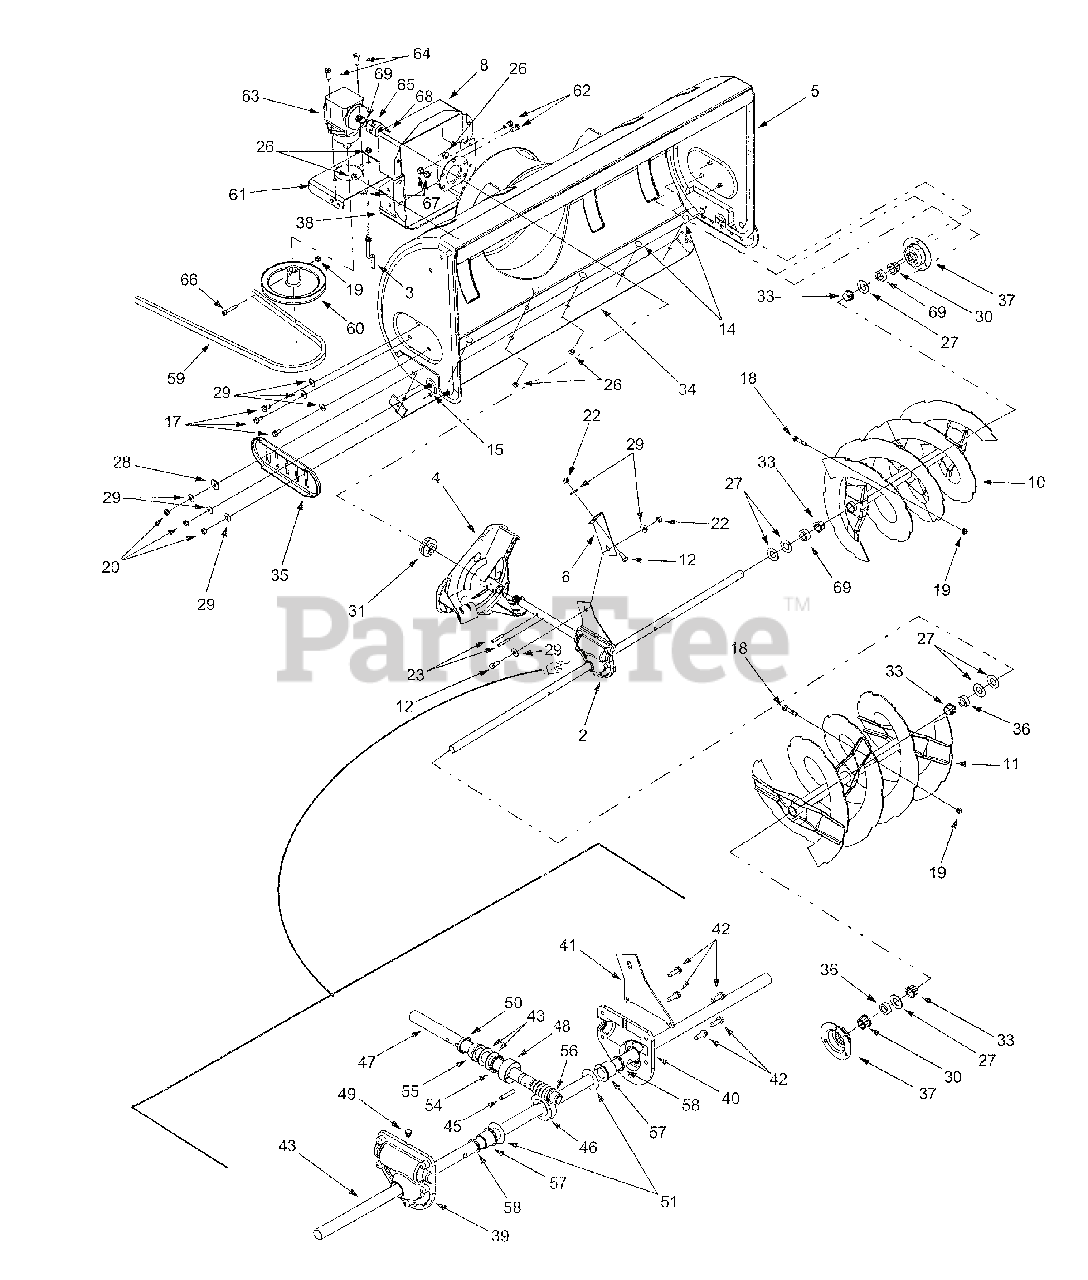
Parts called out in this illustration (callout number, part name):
1	Bearing Housing, 1.85 ID
2	Auger Gear Case
3	Belt Keeper Rod
4	Impeller Assembly, 12"
10	LH Spiral Auger, 40"
11	RH Spiral Auger, 40"
12	Hex Cap Screw, 5/16-24 x .75
13	Carriage Screw, 1/4-20 x .5
14	Carriage Bolt, 5/16-18 x .62
15	Splined Carriage Screw, 5/16-18 x 1.0
16	Carriage Bolt, 5/16-18 x .75
17	Self Tapping Screw, 5/16-18 x .625
18	Shear Bolt, 5/16-18 x 1.5
19	Hex Lock Nut, 5/16-18
20	Hex Nut, 5/16-18
21	Hex Flange Lock Nut, 1/4-20
22	Hex Nut, 5/16-24
23	Spirol Pin, 1/4 x 1-1/2
24	Spirol Pin, .125 x .812
25	Adapter Chute
26	Flange Lock Nut, 5/16-18
27	Flat Washer, .76 x 1.49 x .06
28	Flat Washer, .344 x 1.125 x .12
29	Bell Washer, .340 x .872
30	Hex Flange Bearing, .75 ID
31	Flange Ball Bearing, .75 x 1.85
32	Plastic Bushing, .38
33	Flange Bushing, .80 x .91
34	Skid Plate Bracket, 42"
35	Slide Shoe
36	Spacer, .75 x .125 x .5
37	Hex Bearing Housing, 1.0
38	Skid Plate
39	RH Reducer Housing
40	LH Reducer Housing
42	Self Tapping Screw, 1/4-20 x .75
43	Spiral Axle, 41.5"
44	Hi-Pro Key, 3/16 x 5/8
45	Spring Spirol Pin, .25 x 1.25
46	Worm Gear, 20-tooth
47	Worm Shaft
48	Thrust Collar
49	Grease Plug
50	Grease Seal
51	Flat Washer, .76 x 1.5 x .030
52	Flat Washer, .508 x 1.0 x .020
53	Thrust Washer, .75 x 1.25 x .0615
54	Thrust Bearing, .75 x 1.25 x .078
55	Flange Bearing, .75 x 1.0 x .59
56	Flange Bearing, .503 x .75
57	Flange Bearing, .754 x 1.0 x .925
58	Grease Seal
59	Lower V-belt
60	Drive Pulley, 7"
61	Drive Mounting Bracket
62	Hex Cap Screw, 3/8-16 x .75
63	Right Angle Drive
64	Hex Cap Screw, 3/8-16 x 1.0
65	Coupling
66	Socket Head Cap Screw, 5/16-18 x
67	Flange Lock Nut, 3/8-16
68	Square Key, 3/16 x .75
69	Hi-pro Key, 3/16 x .75
70	Bearing Housing, 1.85 ID
